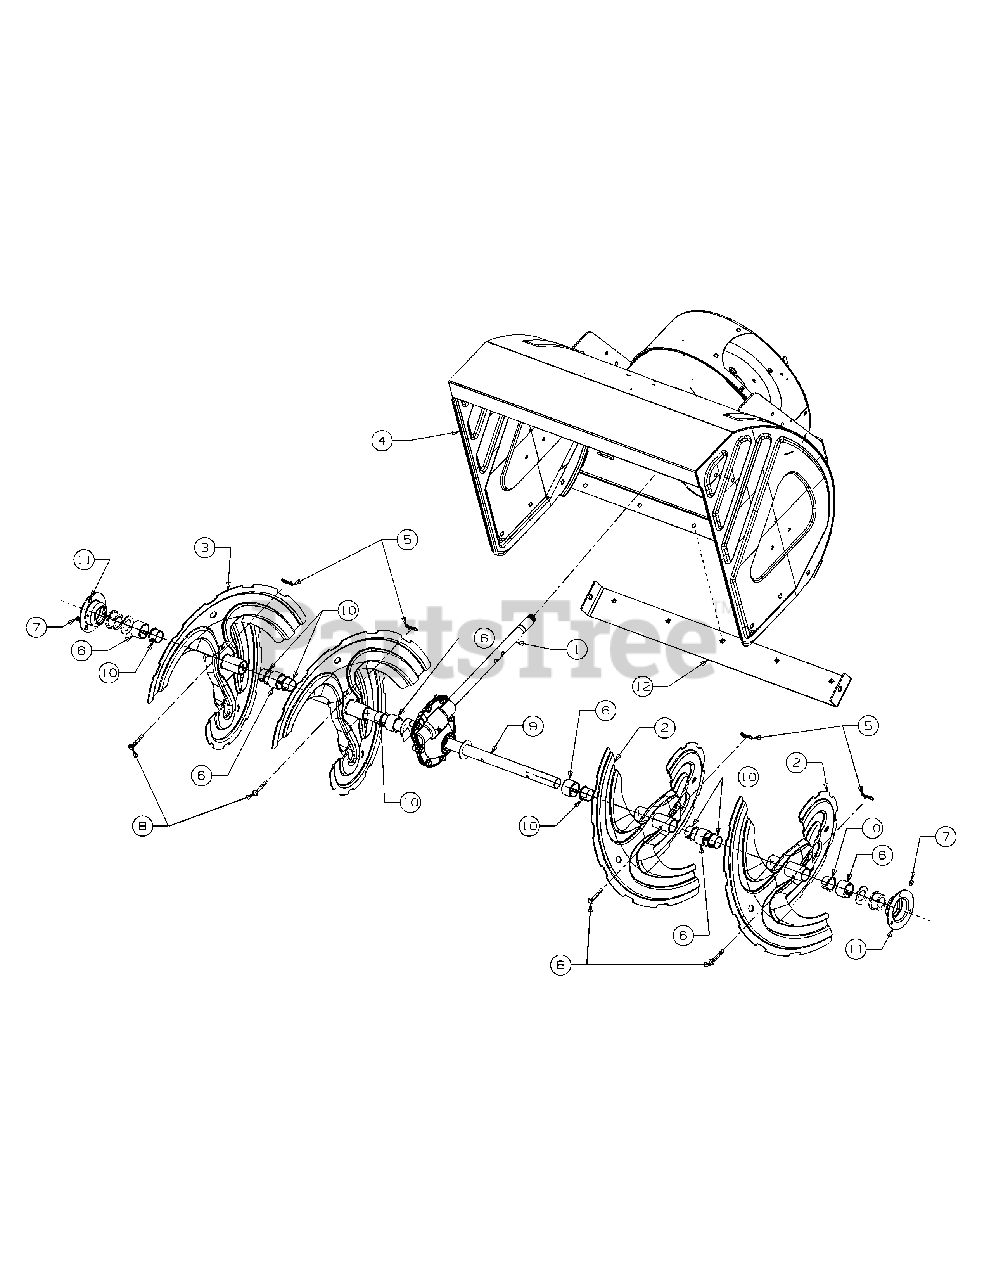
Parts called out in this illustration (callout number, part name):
1	Gear Assy-Auger
2	Spiral Asm:LH 900
3	Spiral Asm:RH 900
4	Housing Assy-Auger
5	Pin-Cotter
6	Spacer: 1.50 Od X
7	Grease Fitting
8	Shear Pin .25X150
9	Axle:Sprl: 29.1
10	Bushing
11	Housing:Bearing
12	Plate-Shave 30"
